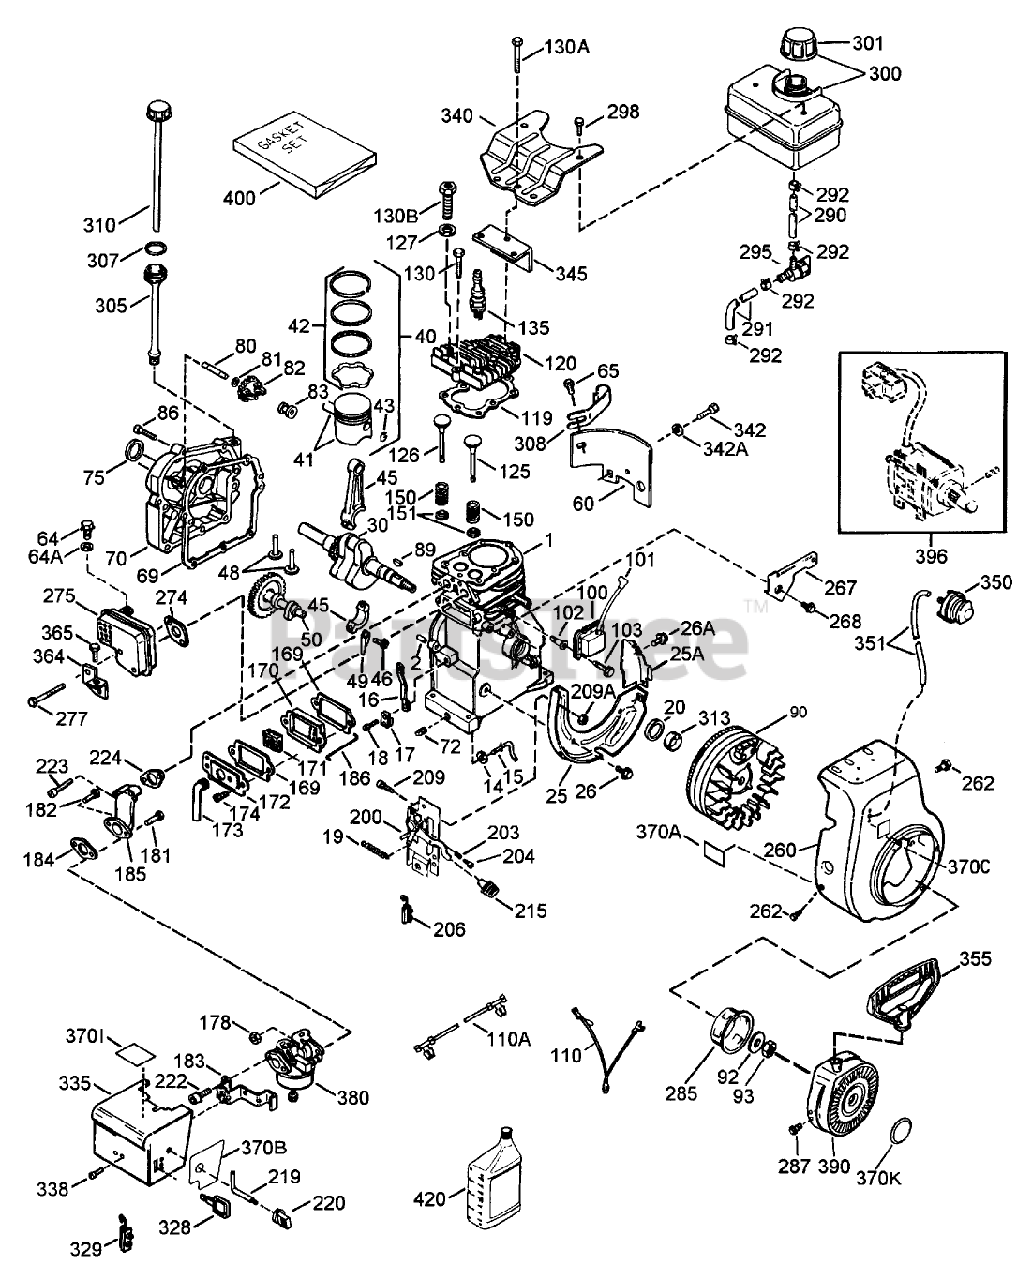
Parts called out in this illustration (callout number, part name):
1	Cylinder Assembly (Incl. Ref. #2, 20, 72
2	Pin-Dowel
14	Washer-Flat
15	Rod-Governor
16	Lever-Governor
17	Clamp-Lever, Governor
18	Screw (T-15, 8-32 x 19/64)
19	Spring-Extension
20	Seal-Oil
25	Baffle-Housing, Blower
25A	Extension-Baffle
26	Screw (1/2-20x5/8)
26A	Screw (8-32 x 21/64)
30	Crankshaft ASM
40	Set-Piston, Pin Ring (Std)
41	Piston Pin Ass-y.(Std.)(Incl. 43)
42	Ring Set (STD)
43	Ring-Retaining, Piston Pin
45	Connecting Rod Assembly (Incl. Ref. #46 49)
46	Bolt-Rod, Connecting
48	Lifter-Valve
49	Dipper-Oil
50	Camshaft
60	Extension-Blower
64	Screw
64A	Washer
65	Screw
69	Gasket-Cover, Cylinder
70	Cover-Cylinder (Incl. Ref. #75 80)
72	Plug-Drain, Oil (SQH 1/4-18)
75	Seal-Oil
80	Shaft-Governor
81	Washer-Flat
82	Governor Gear ASM
83	Spool-Governor
86	Screw (1/4-20 x 1-1/4)
89	Key-Flywheel
90	Flywheel
92	Washer-Belleville
93	Nut-Flywheel
100	Solid State Ignition (Incl. 101)
101	Cover-Spark Plug
102	Stud-Mounting, Solid State
103	Screw (T-15, 10-24 x 15/16)
110	Wire-Ground
110A	Wire-Ground (Green, 5.5)
119	Gasket-Head, Cylinder
120	Head-Cylinder (Incl. Ref. #131)
125	Exhaust Valve (Std.)(Incl. 151)
126	Valve-Intake Standard (Incl. Ref. #151)
127	Washer-Flat
130	Screw (5/16-18x1-1/2)
130A	Screw (5/16-18 X 2)
130B	Screw ( 5/16-18 x 1-1/2)
135	Spark Plug-Resistor (R J19 L M)
150	Spring-Valve
151	Cap-Valve, Spring
169	Gasket-Cover, Valve
170	Body-Breather
171	Element-Breather
172	Cover-Breather
173	Tube-Breather
174	Screw (10-24 x 3/4)
178	Nut and Lock Washer (1/4-28)
181	Screw (1/4-28 x 1-11/16)
183	Bracket-Choke
184	Gasket
185	Pipe-Intake
186	Link-Governor to Throttle
200	Control Assembly (Incl. Ref.# 203, 204, 206, 209 209A)
203	Spring-Compression
204	Screw (T-10, 5-40x7/16)
206	Terminal
209	Screw
209A	Nut-Lock
215	Knob-Control
219	Rod-Choke
220	Knob-Control
222	Screw (10-32 x 1/2)
223	Screw (1/4-20 x 1-19/32)
224	Gasket-Intake
260	Housing-Blower
262	Screw (1/4-20 x 1/2)
267	Bracket-Hold Down
268	Screw (10-24 x 9/16)
274	Gasket-Exhaust
275	MANUAL
277	Screw-Fil. Hd.
285	Cup-Starter
287	Screw (8-32 x 21/64)
290	Line-Fuel
291	Line-Fuel (8.62)
292	Clamp-Line, Fuel
295	Valve-Shut Off, Fuel
298	Screw (1/4-15x7/8)
300	Tank Assembly-Fuel (Incl. Ref. #250 253)
301	Cap-Fuel
305	Tube-Fill, Oil
307	O-Ring
308	Clip-Tube, Fill
310	Dipstick
313	Spacer
328	Key-Ignition
329	Terminal
335	Cover-Carburetor
338	Screw (8-32 X 5/16)
340	Plate-Fuel Tank
342	Screw
342A	Washer
345	Baffle-Heat
350	Primer ASM
351	Line-Primer
355	Handle-Starter, Mitten Grip
364	Bracket-Cover, Carburetor
365	Screw (10-24 x 3/8)
370A	Decal-Lubrication
370B	Decal-Control
370C	Decal-Primer, International Symbol
370I	Decal-Warning (Bilingual)
370K	Decal-Tecumseh Logo for Top of Recoil Starter
380	Carburetor (Incl. Ref. #1-48)
390	Starter-Rewind
396	Starter-Electric (110 Volt)
400	Gasket Set (Incl. Parts Marked *)(26756 (1), 27234A (2), 27272A (1), 27677A (1) 29673 (1), 36443 (1), 33670A (1), 33673A (1)
420	Oil-Engine (SAE 5W30)
